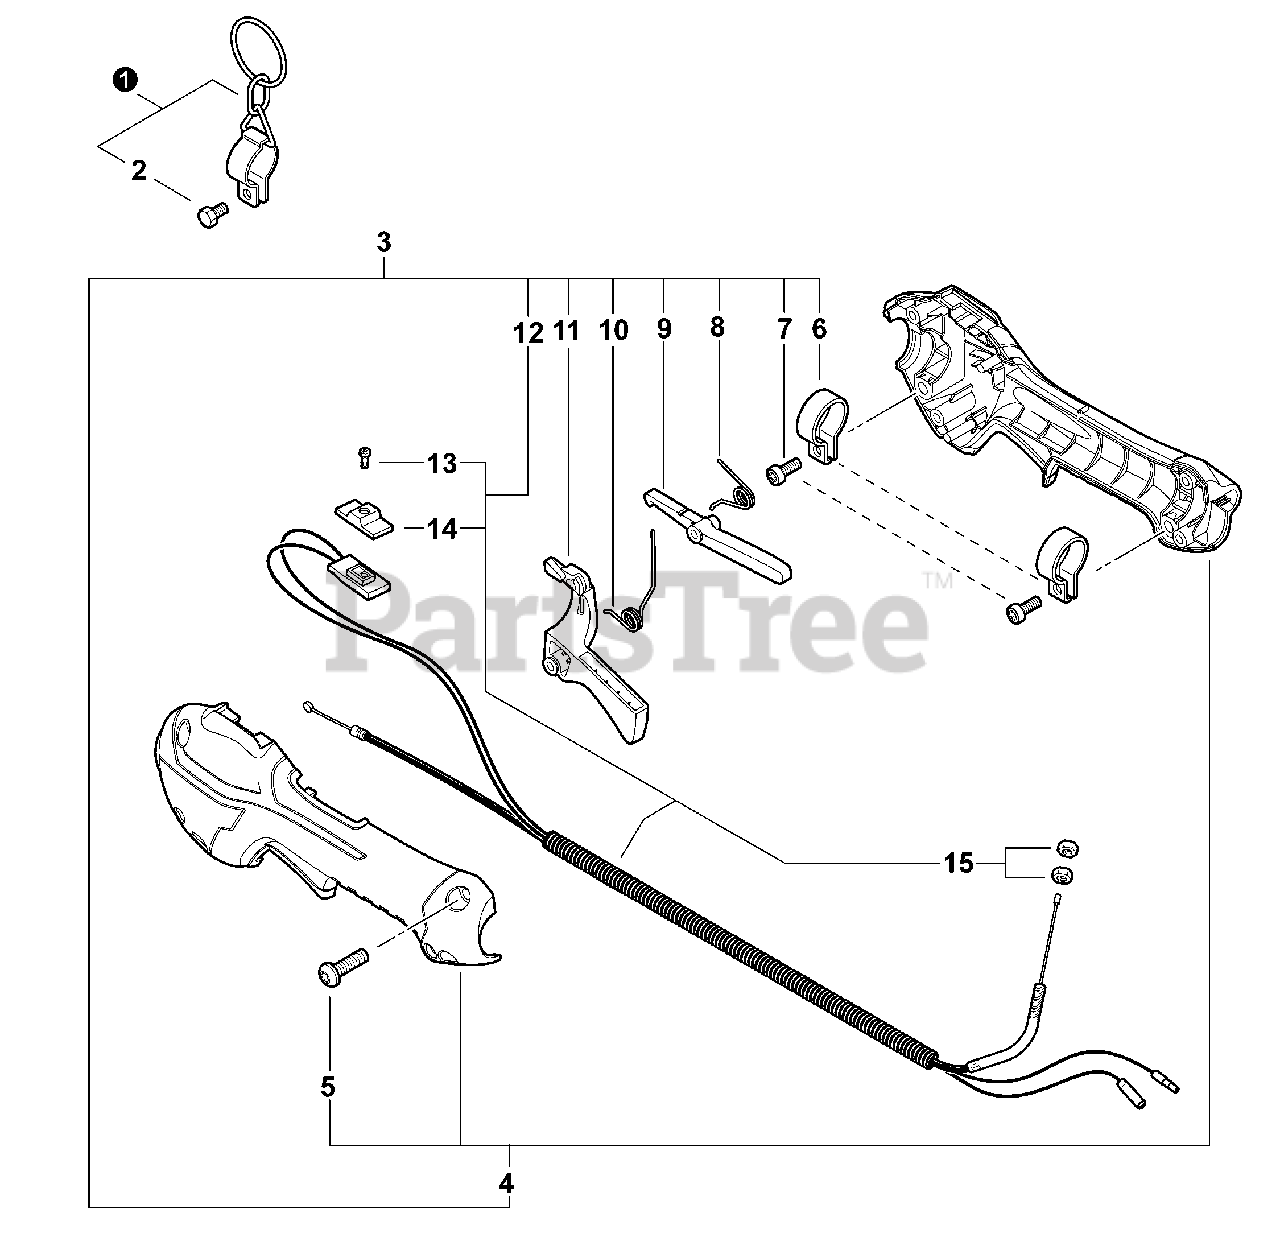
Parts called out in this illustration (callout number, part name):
1	HANGER SET, HARNESS
2	BOLT 5×12
3	CONTROL HANDLE ASSY
4	CONTROL HANDLE KIT
5	BOLT, TORX 5×16
7	BOLT, TORX 5×16
8	SPRING, TORSION
9	LEVER, THROTTLE LOCKOUT
10	SPRING, TORSION
11	TRIGGER, THROTTLE
12	CABLE ASSY, CONTROL
13	SCREW 3×10
14	KNOB, SWITCH - ORANGE
